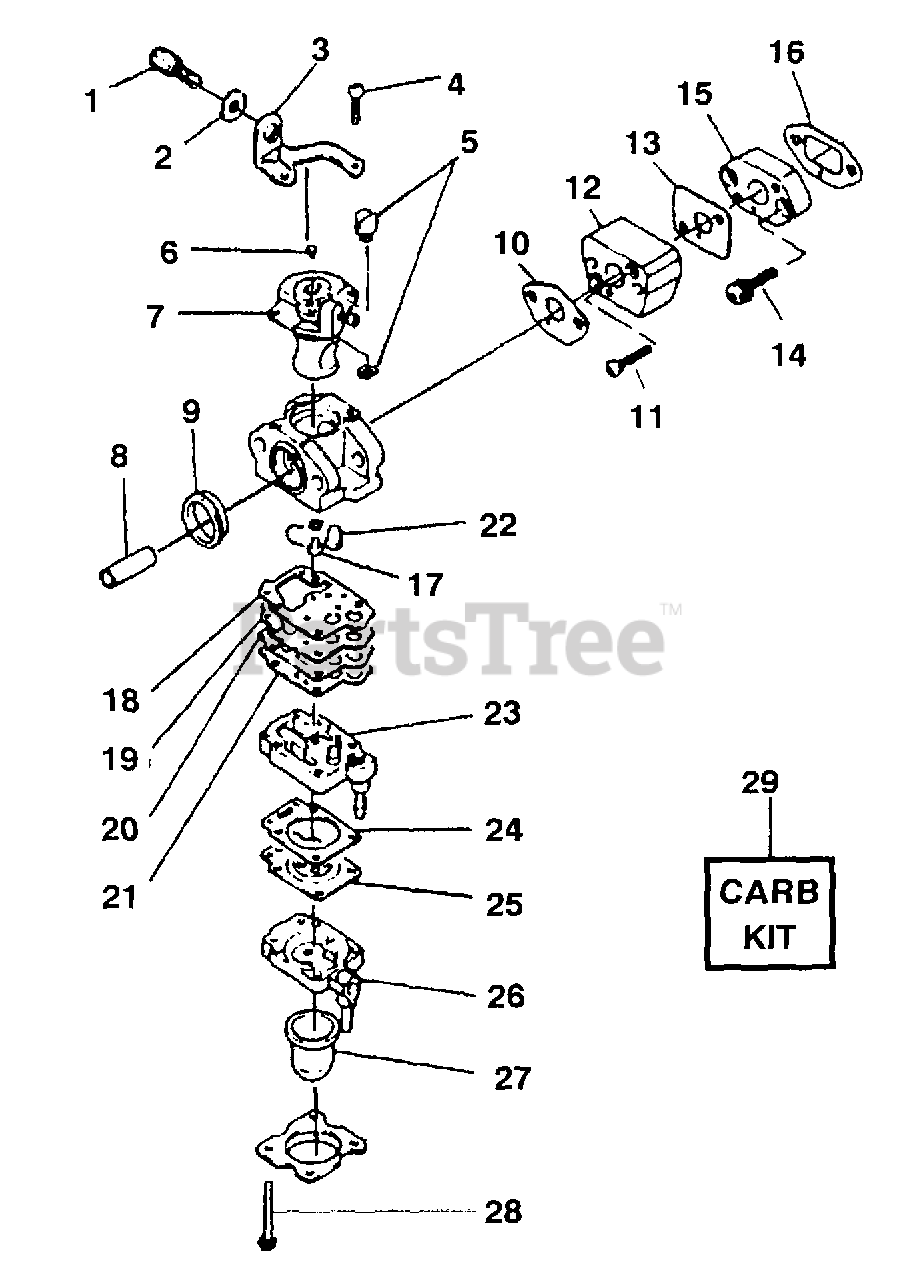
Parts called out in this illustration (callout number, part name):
1	CABLE ADJUSTER
2	NUT
4	SCREW
7	THROTTLE VALVE
10	GASKET, CARB
11	SCREW & WASHER
12	INSULATOR
14	SCREW & WASHER
16	GASKET, CARB
17	MAIN JET
18	GASKET, PUMP
19	DIAPHRAGM
22	SCREEN, INLET
23	BODY ASSY
24	GASKET DIAPH.
25	DIAPHRAGM
26	BODY, PRIMER
27	PUMP, PRIMER
28	SCREW
